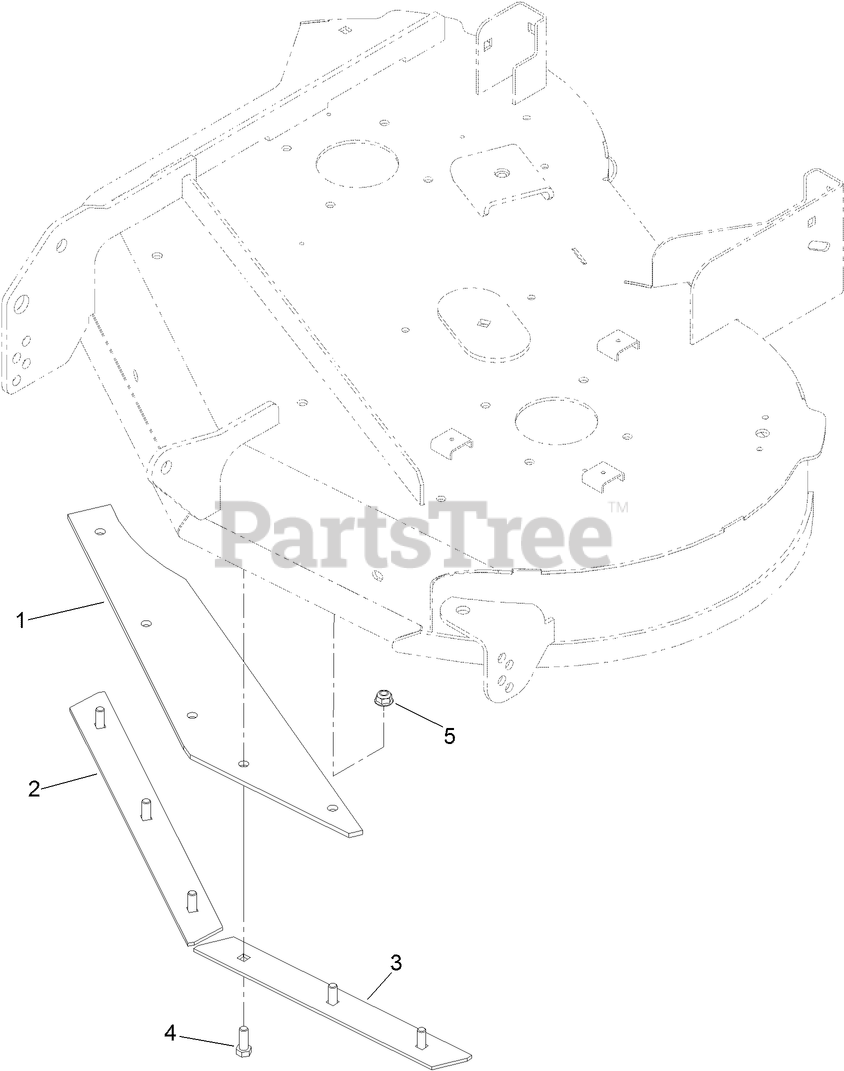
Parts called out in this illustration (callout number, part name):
1	SKIRT-RUBBER
4	SCREW-HH
5	NUT-HF, NI
